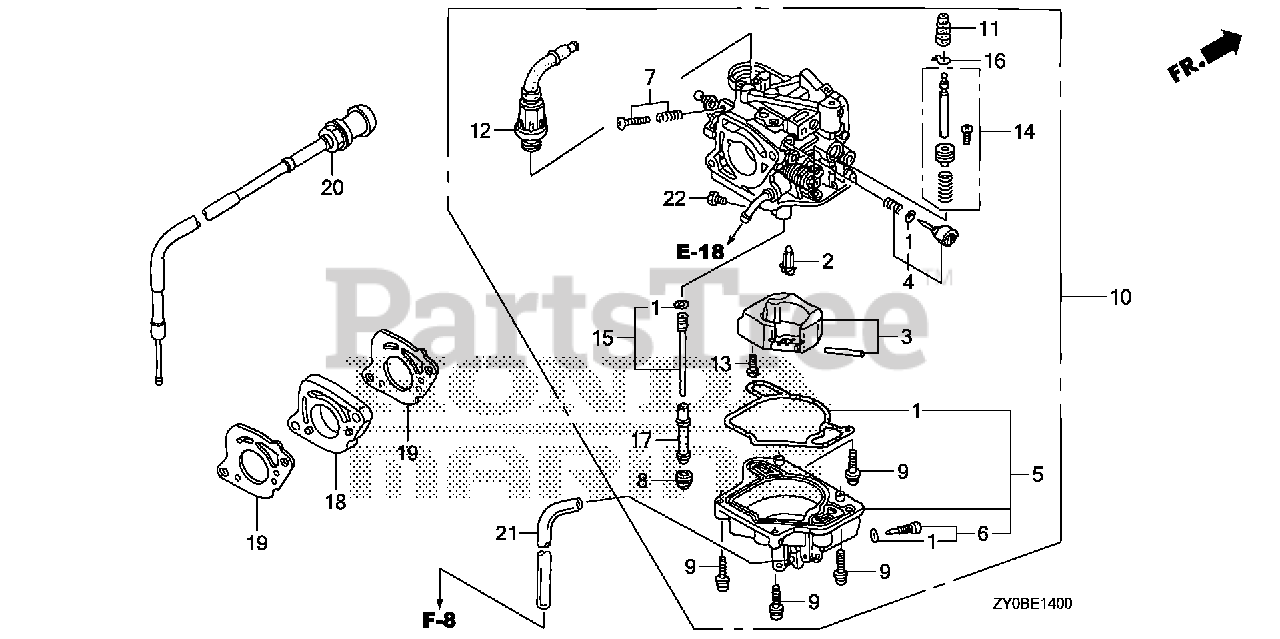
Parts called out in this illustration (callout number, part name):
1	GASKET SET
2	VALVE SET, FLOAT
5	CHAMBER SET, FLOAT
6	SCREW SET, DRAIN
8	SCREW, PLUG
9	SCREW-WASHER
10	CARBURETOR ASSY. (BJ11A A)
12	VALVE SET, STARTER
13	SCREW, PAN
14	PLUNGER SET, ACCELERATOR PUMP
15	JET SET (#52)
16	CLIP, TUBE
17	NOZZLE, MAIN
18	INSULATOR, CARBURETOR
19	GASKET, CARBURETOR
20	CABLE, CHOKE
21	BULK HOSE, VINYL (4X7X8000) (4X7X200)
22	JET, MAIN (#98)
22	JET, MAIN (#100)
22	JET, MAIN (#102)
